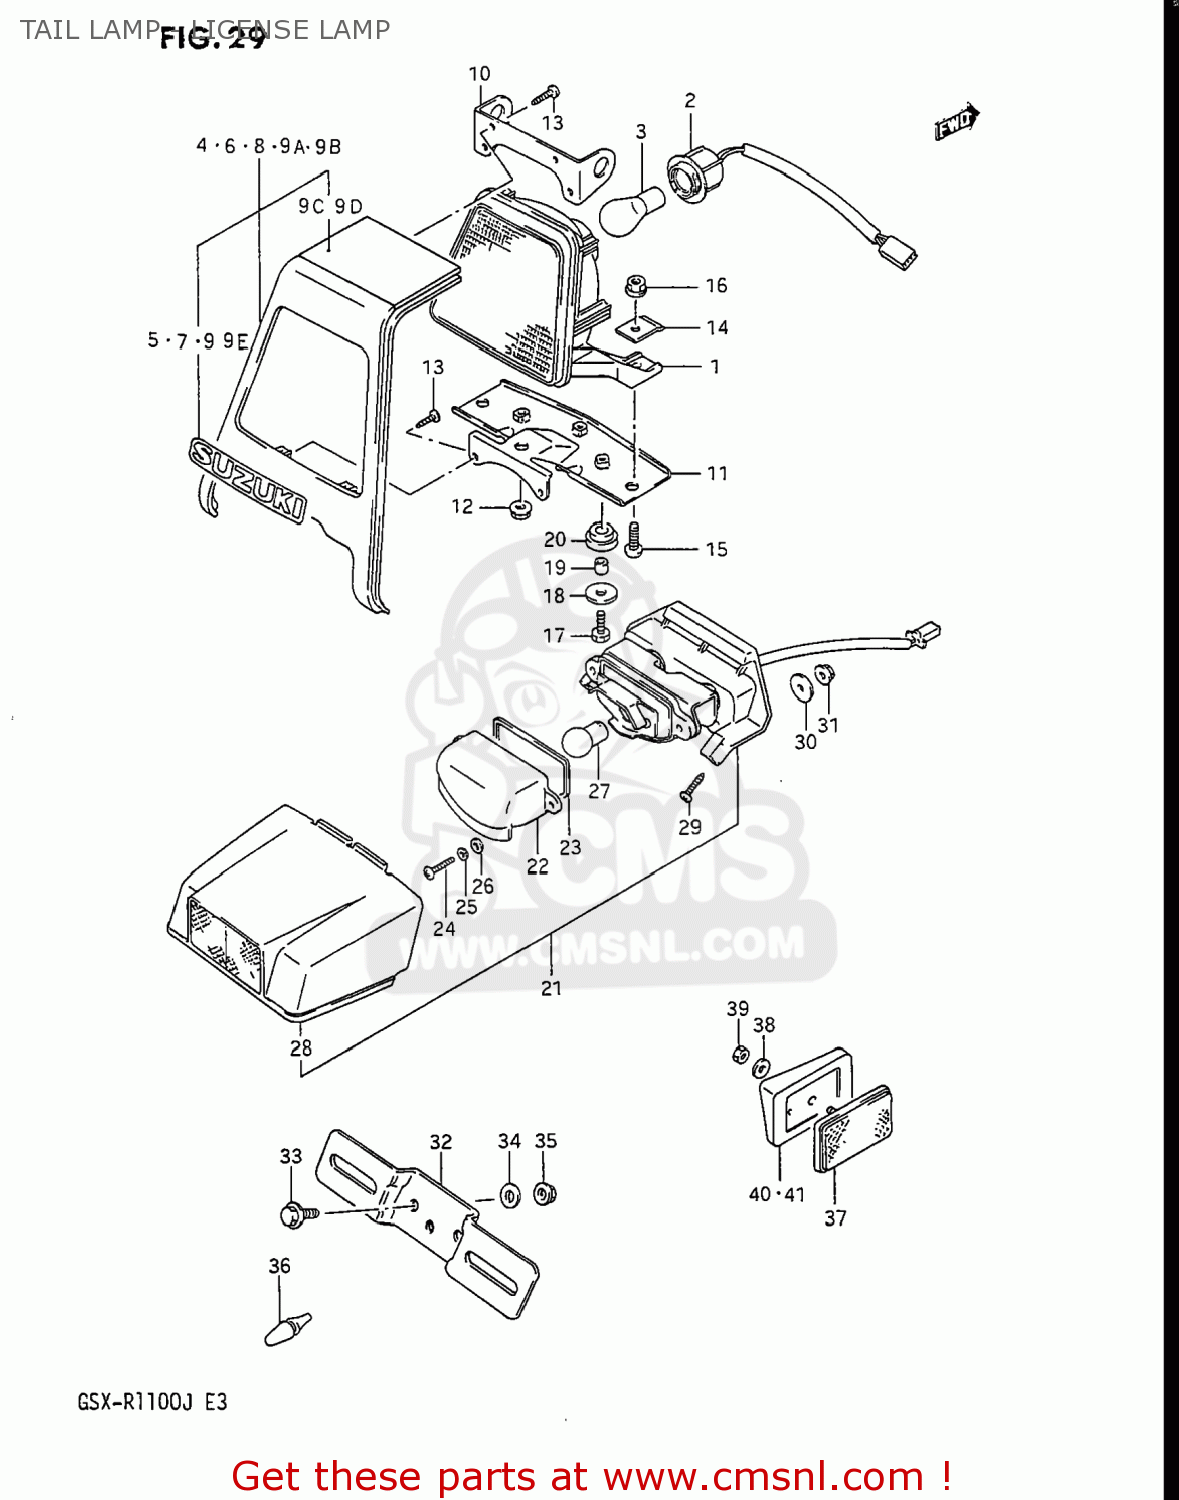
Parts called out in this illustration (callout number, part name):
1	LAMP UNIT
2	SOCKET & CORD ASSEMBLY
3	BULB(12V23/8W,TOKAI DENSO)
4	COVER,TAIL LAMP
5	EMBLEM
6	COVER,TAIL LAMP
7	EMBLEM
8	COVER,TAIL LAMP
9	EMBLEM(WHITE)
9A	COVER,TAIL LAMP
9B	COVER,TAIL LAMP
9C	TAPE,REAR COMBINATION LAMP
9D	TAPE,REAR COMBINATION LAMP
9E	EMBLEM
10	PLATE
11	BRACKET
12	NUT
13	SCREW
14	PLATE,TAIL LAMP
15	SCREW
16	NUT
17	BOLT,M6X1X20
18	WASHER
19	SPACER (6.1X9X7.5)
20	CUSHION
21	LAMP ASSEMBLY,LICENSE
22	LENS,LICENSE LAMP
23	GASKET,LICESE LAMP (NAS)
24	SCREW
25	WASHER,LOCK 4M
26	WASHER 4MM
27	BULB
28	COVER,LICENSE LAMP
29	SCREW
30	WASHER (5.5X20X1.2)
31	NUT
32	BRACKET,LICENSE PLATE
33	BOLT
34	WASHER
35	NUT
36	CUSHION
37	REFLECTOR,REFLEX
38	WASHER(5.2X16X1)
39	NUT
40	SPACER,REAR SIDE,REAR,RIGHT
41	SPACER,REAR SIDE,REAR,LEFT
